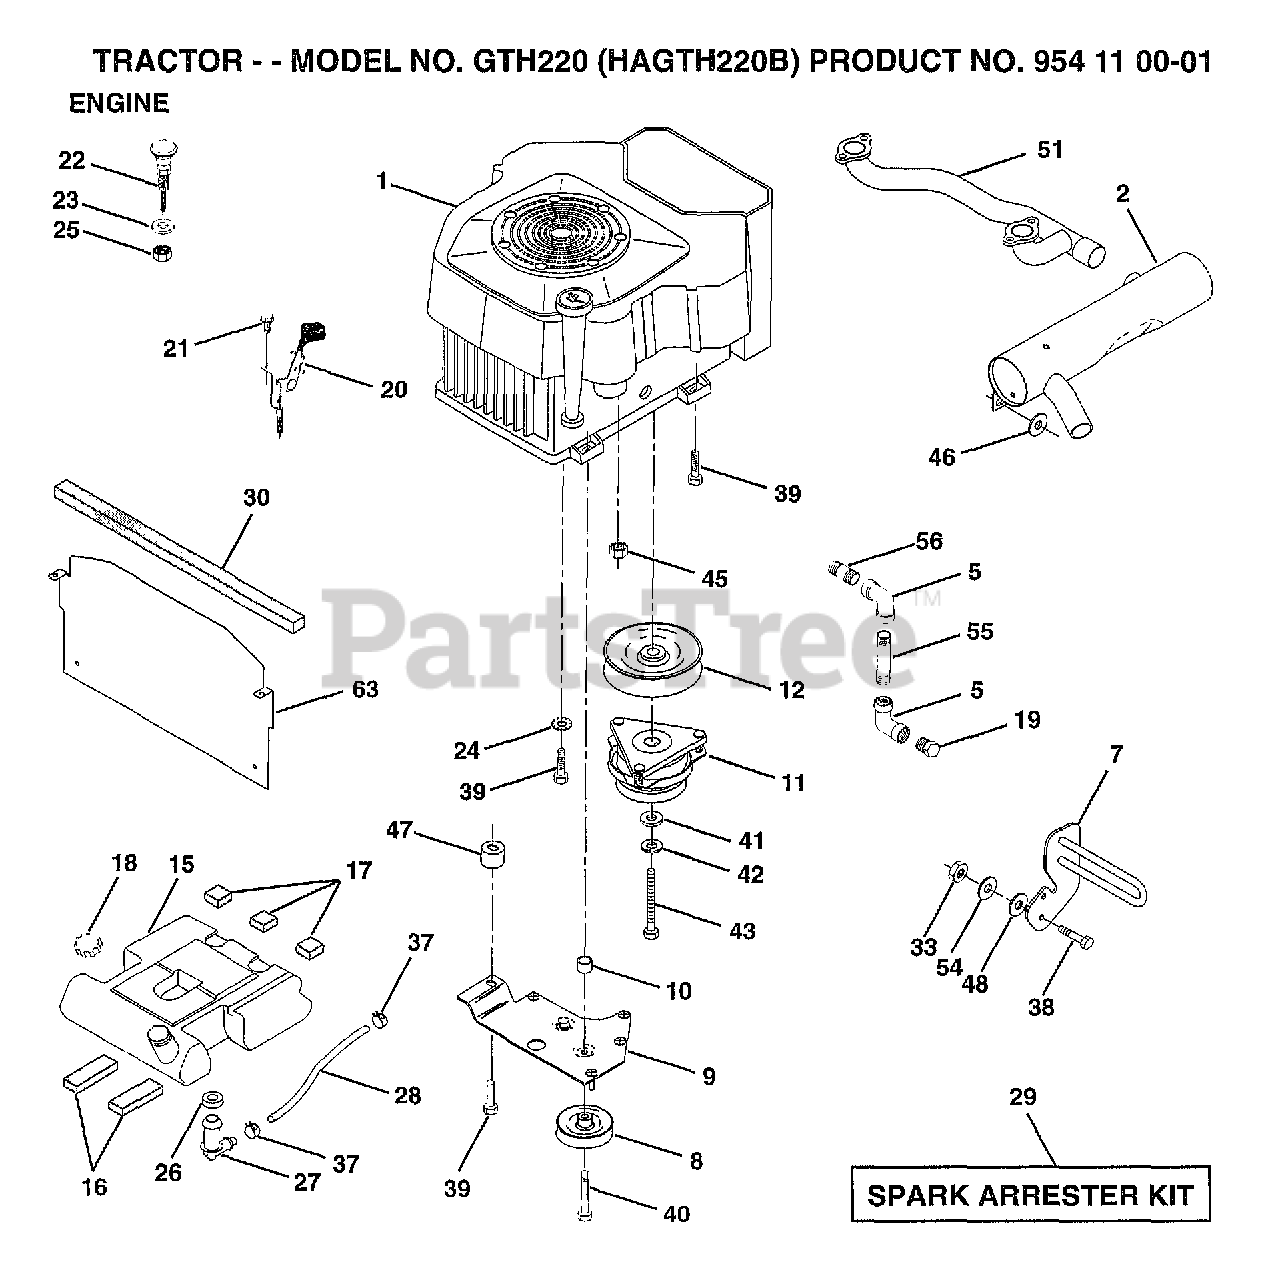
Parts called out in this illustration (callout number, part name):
1	ENGINE, KOHLER
2	MUFFLER VGT CYLINDER
5	ELBOW STD 90 DEGREE 3/8-18 NPT
19	PLUG OIL DRAIN
21	SCREW HEX THD CUT 1/4-20X5/8 T
23	WASHER 13/32 X 13/16 X 16 GA
24	WASHER LOCK
25	NUT, KEPS 3/8-24 UNF
33	LOCKNUT
38	BOLT, FIN HEX 3/8-16 UNC X 1-1/2
39	SCREW, TT 3/8-16 X 2-1/4 UNC
40	SCREW, TT 3/8-16 X 4 UNC
42	WASHER LOCK HVY HLCL SPR 7/16
46	WASHER
48	WASHER, 13/32 X 1-1/4 X 7 GA.
51	PIPE CROSSOVER
54	WASHER, FLAT 13/32 X 7/8 X 14 GA.
55	NIPPLE, PIPE 4-1/2
56	NIPPLE, PIPE 3/8 NPT X 1.00
